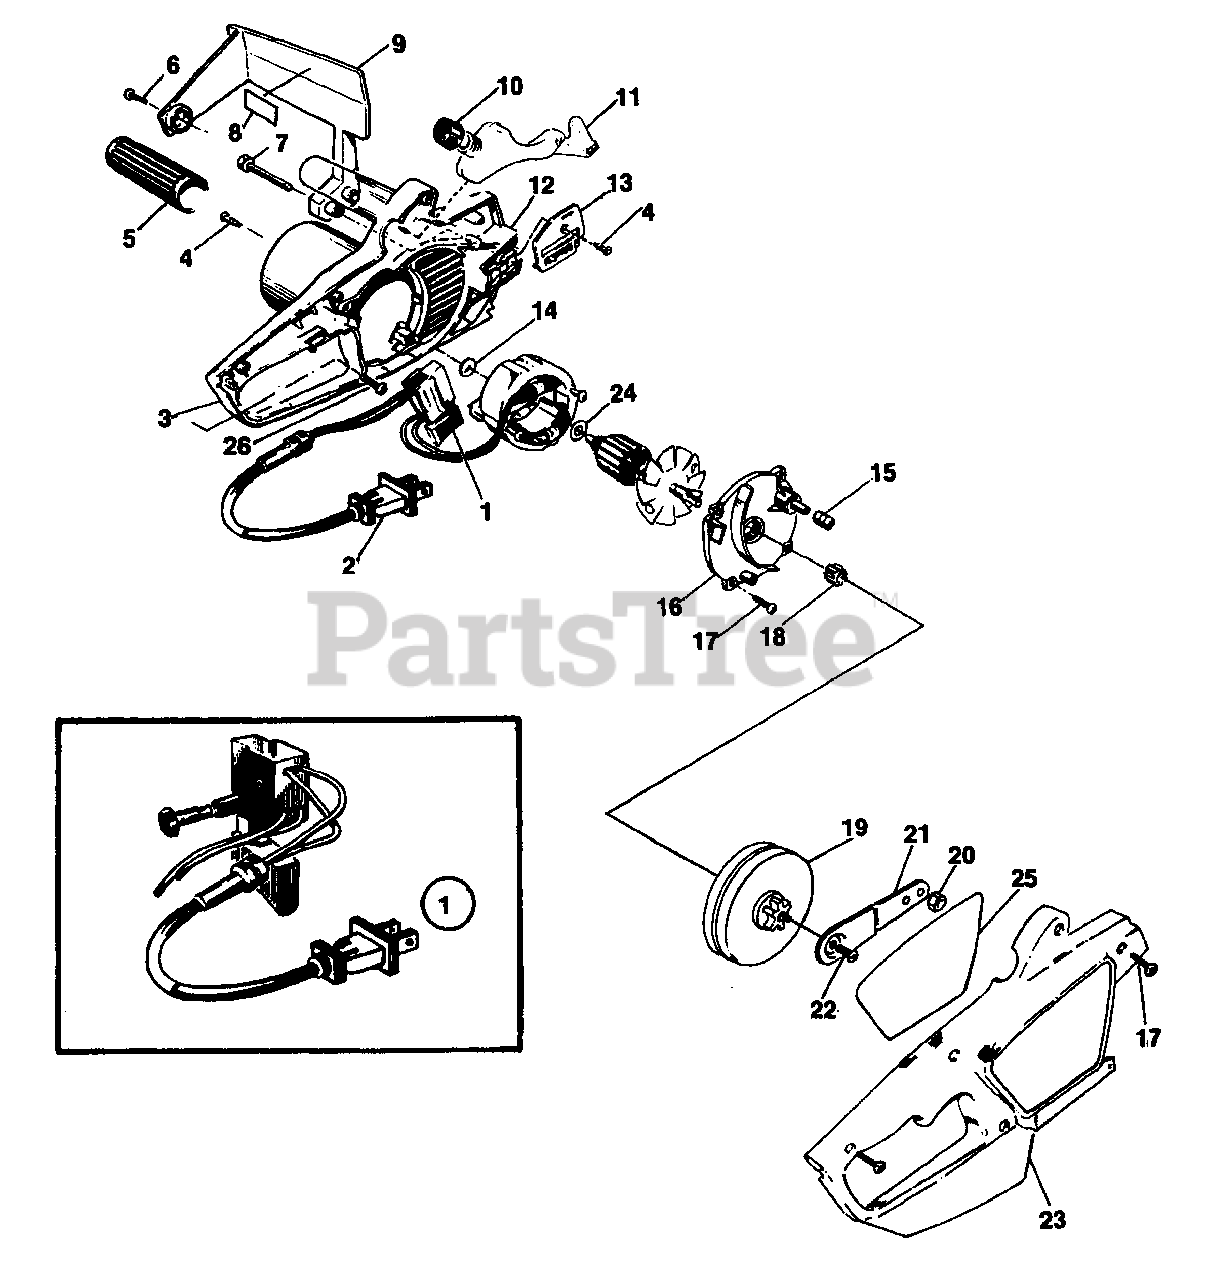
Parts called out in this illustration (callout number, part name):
1	SWITCH - Lock-off
3	HOUSING ASSY. - Motor 12"
4	SCREW - Tap, Flat Hd.
5	GRIP - Handle, Front
6	SCREW - Pan-Hd.
7	BOLT - Hex-Hd.
8	DECAL - Hand Guard
9	GUARD - Handle, Front
10	CAP - Reservoir, Oil
11	RESERVOIR - Oil
12	HOUSING ASSY. - Gear
13	PLATE ASSY - Adjusting
14	DISC THRUST
15	BEARING - Roller, Sprocket
16	PLATE - Bearing
17	SCREW - Tap. Pan-Hd. 8-16x.88
18	GEAR - Drive
19	GEAR - Internal
20	NUT - Hex
21	SUPPORT - Sprocket
22	SCREW - Shoulder, Pan-Hd.
23	COVER - Side
24	WASHER - Thrust
25	COVER - Sprocket
26	SCREW - Tap, Pan-Hd.
